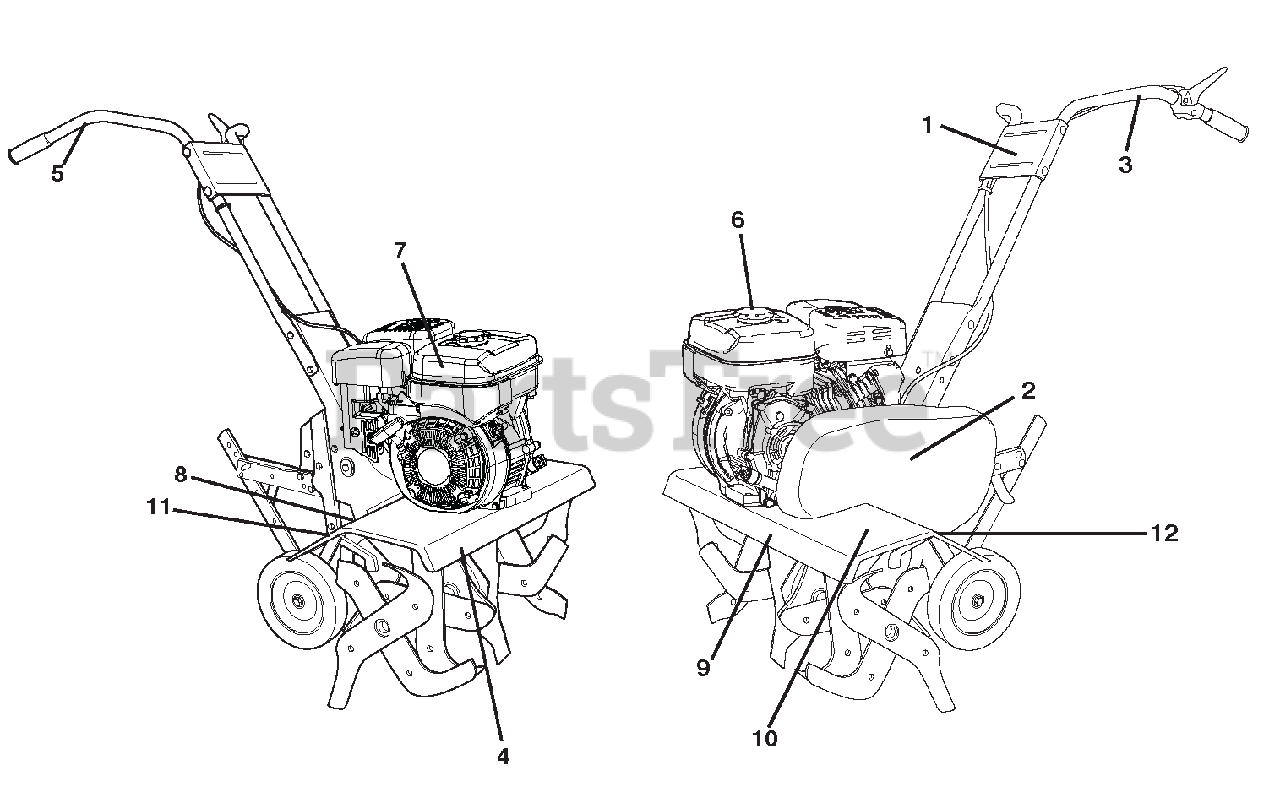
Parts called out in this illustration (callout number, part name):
1	DECAL, CONSOLE
2	DECAL, BELT GUARD
3	Decal, Tine Control
4	DECAL, SUBARU TINE SHIELD
5	Decal, Hand Placement
6	DECAL, ETHANOL
7	Decal, Spark Arrester
8	Decal, Warning
9	DECAL, 24" TINE SHIELD
10	DECAL, TINE SHIELD GEAR
11	Decal, Warning, Rotating Tines
12	Decal, Read Owners Manual
